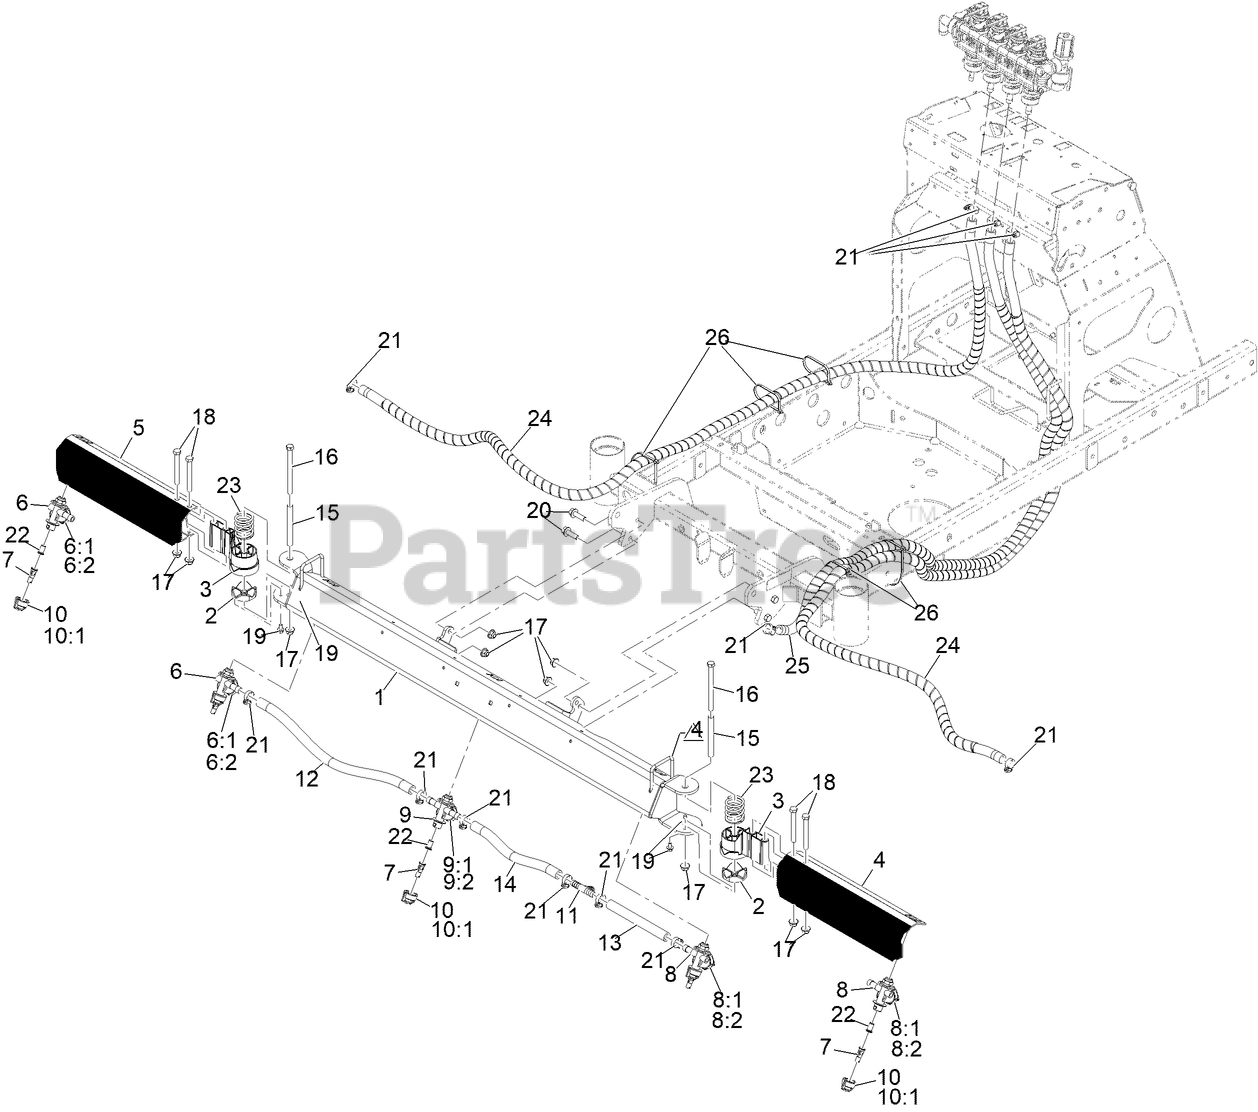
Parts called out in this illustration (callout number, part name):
1	BOOM-CENTER, MAX
2	BOOM-PIVOT
3	HINGE-BOOM
4	BOOM-WING, LH
5	BOOM-WING, RH
6	BODY-NOZZLE, RIGHT
6:1	CAP-SPRAYER NOZZLE
6:2	DIAPHRAGM-SPRAYER NOZZLE
7	TIP-SPRAY, 025
8	BODY-NOZZLE, LEFT
8:1	CAP-DIAPHRAM
8:2	DIAPHRAGM FOR CHECK VALVE
9	BODY-NOZZLE, CENTER
9:1	DIAPHRAGM FOR CHECK VALVE
9:2	CAP-DIAPHRAM
10	CAP-NOZZLE
10:1	SEAT-GASKET
11	FITTING-TEE
12	HOSE-SPRAY
13	HOSE-SPRAY
14	HOSE-SPRAY
15	SPACER-BOOM, PIVOT
16	SCREW-HH
17	Nut-Hex Flange
18	SCREW-HH
19	SCREW-HWH
20	SCREW-HHF
21	CLAMP-HOSE
22	STRAINER-NOZZLE, 50M 5PSI
23	SPRING-COMPRESSION
24	HOSE-SPRAY, WRAPPED
25	HOSE-SPRAY, WRAPPED
26	TIE-CABLE
